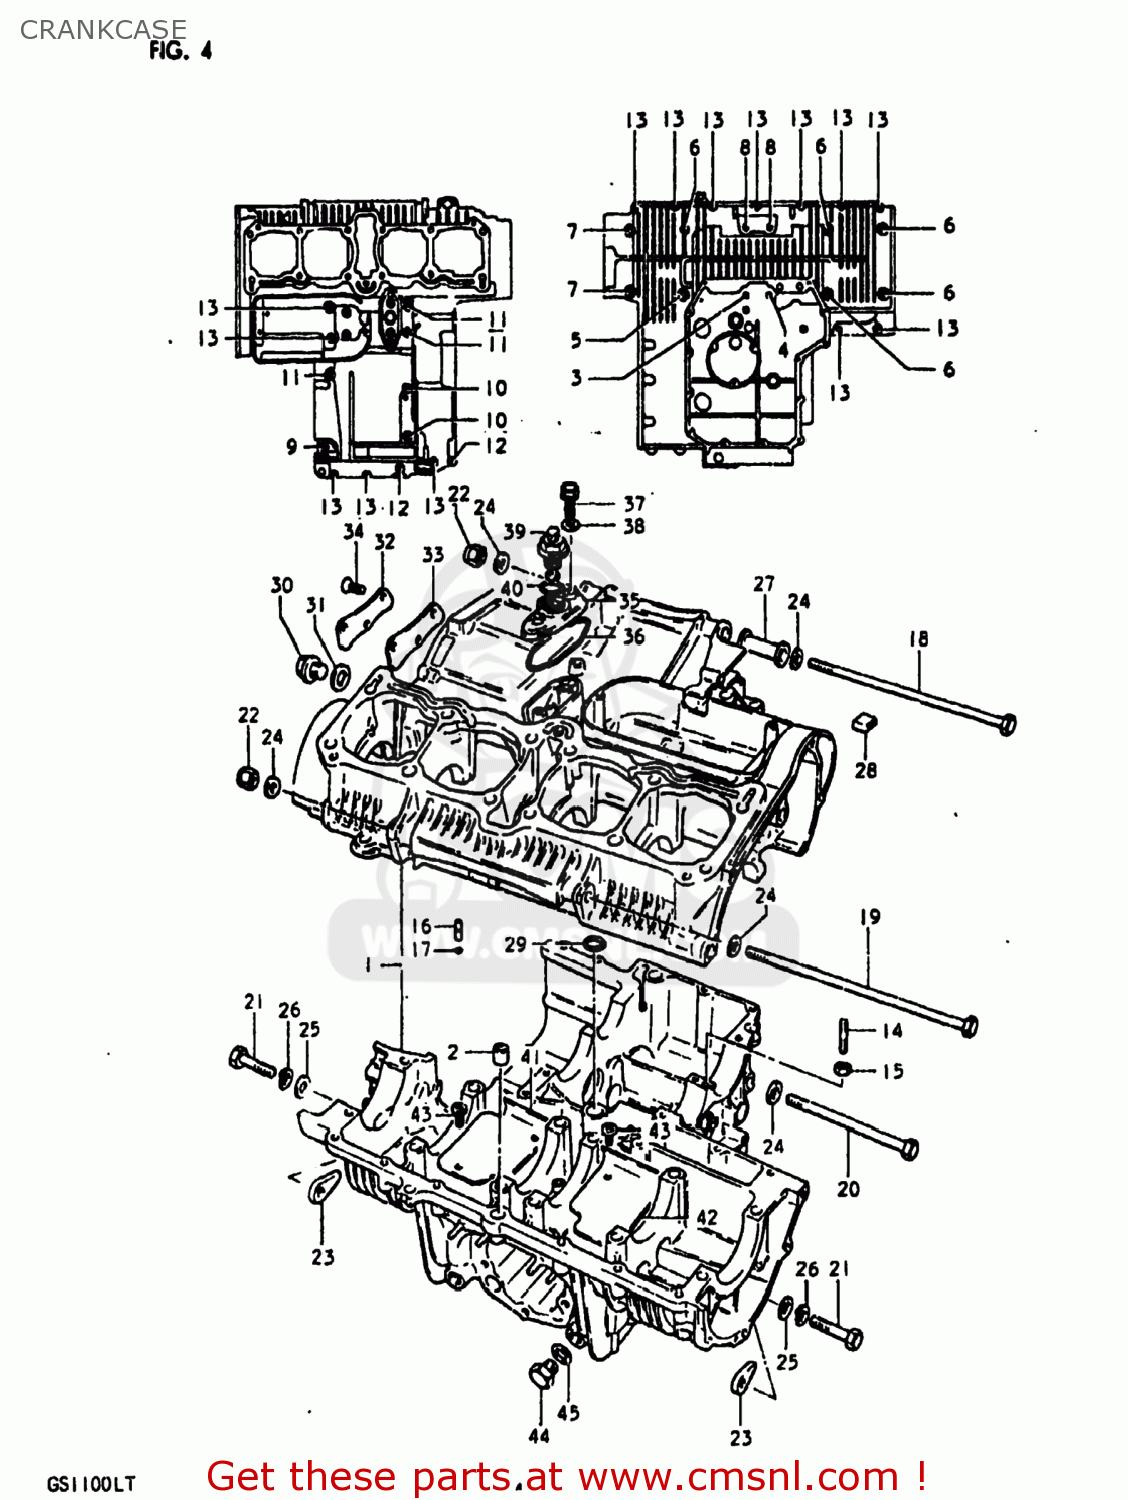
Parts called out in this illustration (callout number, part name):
1	CRANKCASE SET
2	PIN
3	BOLT
4	BOLT
5	BOLT
6	BOLT 8X90
7	BOLT 8X65
8	BOLT
9	BOLT
10	BOLT
11	BOLT (6X75)
12	BOLT
13	BOLT
14	STUD BOLT
15	NUT
16	UNION
17	O-RING
18	BOLT 10X230
19	BOLT 10X250
20	BOLT(10X165)
21	BOLT 10X60
22	NUT
23	NUT
24	WASHER
25	WASHER(10.5X20X3.2)
26	LOCK WASHER
27	SPACER,ENGINE MOUNT
28	PAD,CYLINDER
29	O RING(D:3.2,ID:12.9)
30	PLUG (14X12)
31	GASKET(14X19.2X2) (NAS)
32	CAP,OIL GALLERY
33	GASKET,OIL GALLERY (MCA)
34	SCREW
35	HOUSING,OIL PRESSURE SWITCH
36	O RING,PRESSURE SWITCH HOUSING
37	BOLT
38	GASKET (NAS)
39	SWITCH ASSEMBLY
40	O RING(D:1.9,ID:18.8)
41	PLATE,OIL SEPARATOR
42	PLATE,OIL SEPARATOR
43	SCREW
44	PLUG
45	GASKET 14X18X1.5
